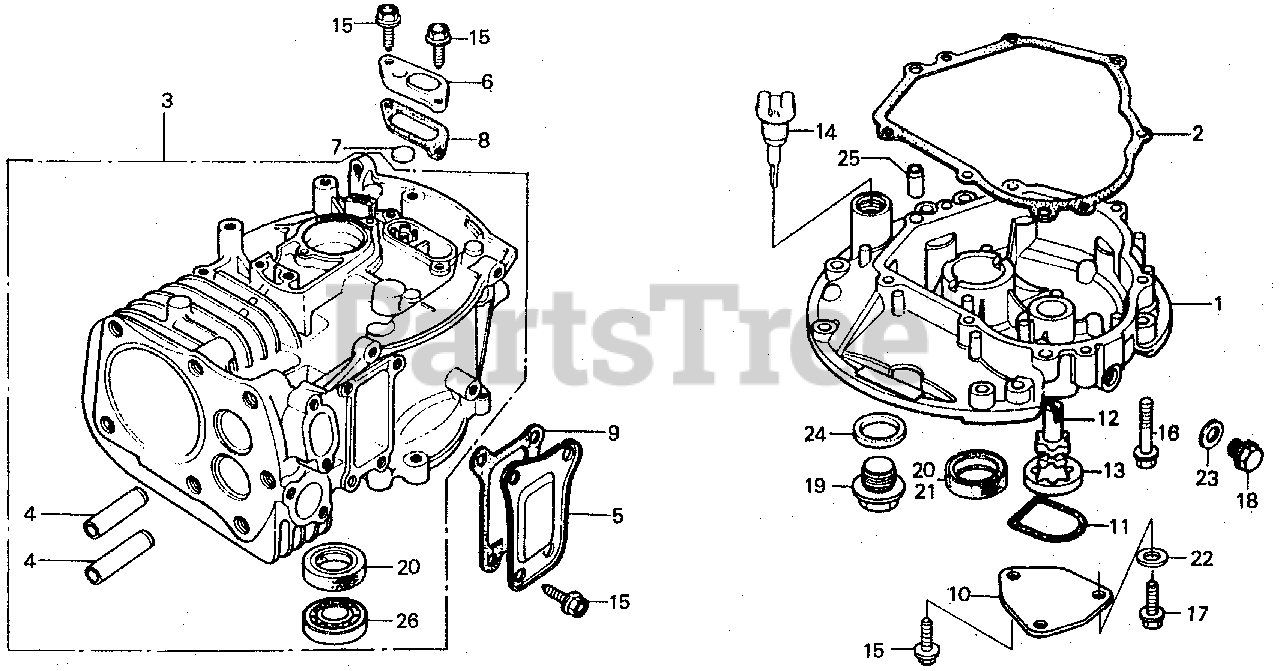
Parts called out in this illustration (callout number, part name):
2	GASKET, OIL PAN (NOT AVAILABLE)
3	CYLINDER ASSY.
4	GUIDE, VALVE (OS)
5	COVER, TAPPET
6	CAP, BREATHER CHAMBER
7	VALVE, BREATHER
8	GASKET, BREATHER CAP
9	GASKET, TAPPET COVER
10	COVER, OIL PUMP
11	O-RING, COVER
12	ROTOR (INNER)
13	ROTOR, OIL PUMP (OUTER)
14	CAP, OIL FILLER
15	BOLT, FLANGE (6X12) (CT200)
16	BOLT, FLANGE (6X32)
17	BOLT, FLANGE (6X16)
18	BOLT, DRAIN PLUG
19	BOLT, DRAIN PLUG (NOT AVAILABLE)
20	OIL SEAL (25X41X6)
21	OIL SEAL (25X38X7)
21	OIL SEAL (25X38X7) (ARAI)
22	WASHER, PLAIN (6MM)
23	WASHER, DRAIN PLUG (12MM)
24	WASHER, DRAIN PLUG (20MM)
25	PIN A, DOWEL (8X14)
26	BEARING, RADIAL BALL (6205)
